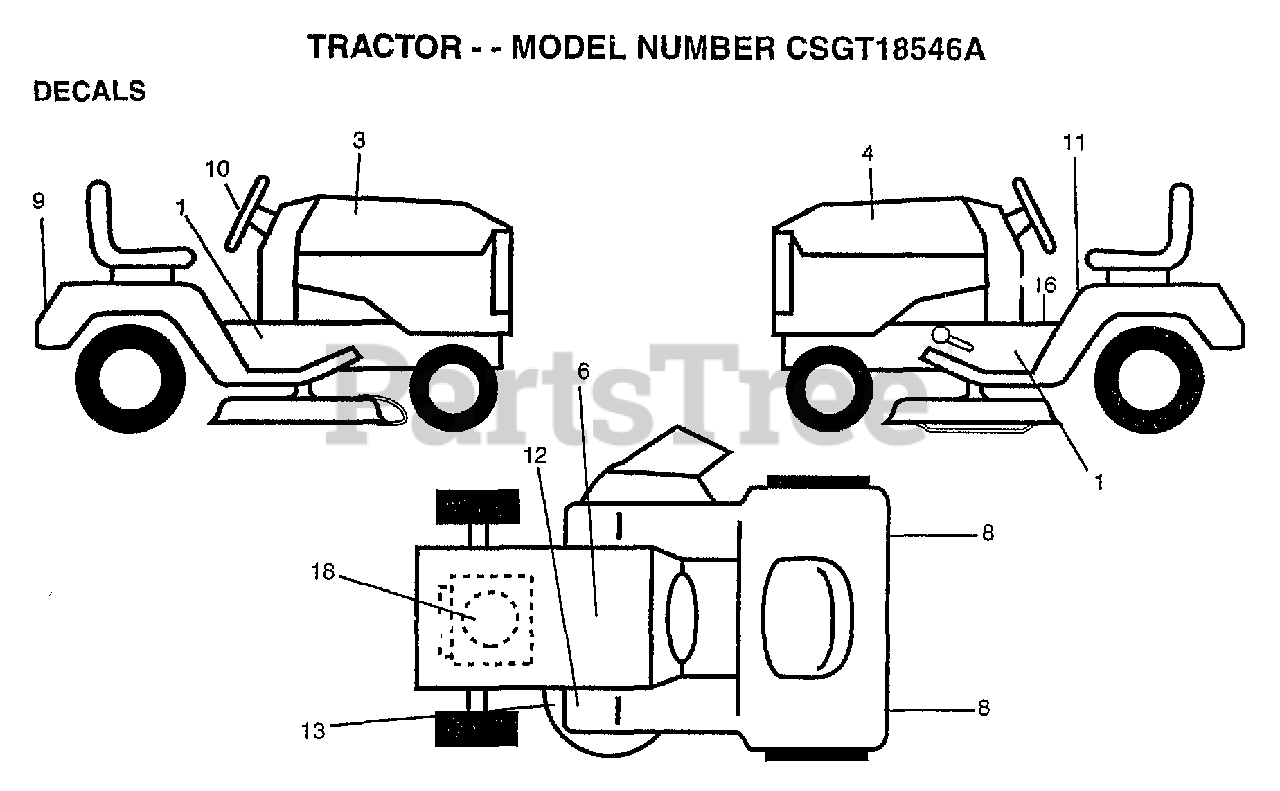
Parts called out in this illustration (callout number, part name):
1	"DECAL CHASSIS,46"""
3	DECAL HOOD RH18.5
4	DECAL HOOD LH18.6
6	DECAL.BATRY.3-3908
8	REFLECTOR-TAIL YT
9	DECAL FENDER
10	"DECAL INSERT,STRG"
11	"DECAL DANGER,FEND"
13	"DECAL.V.BELT.44"""
16	"DECAL DASH,OPER."
18	DECAL, HP, ENGINE
